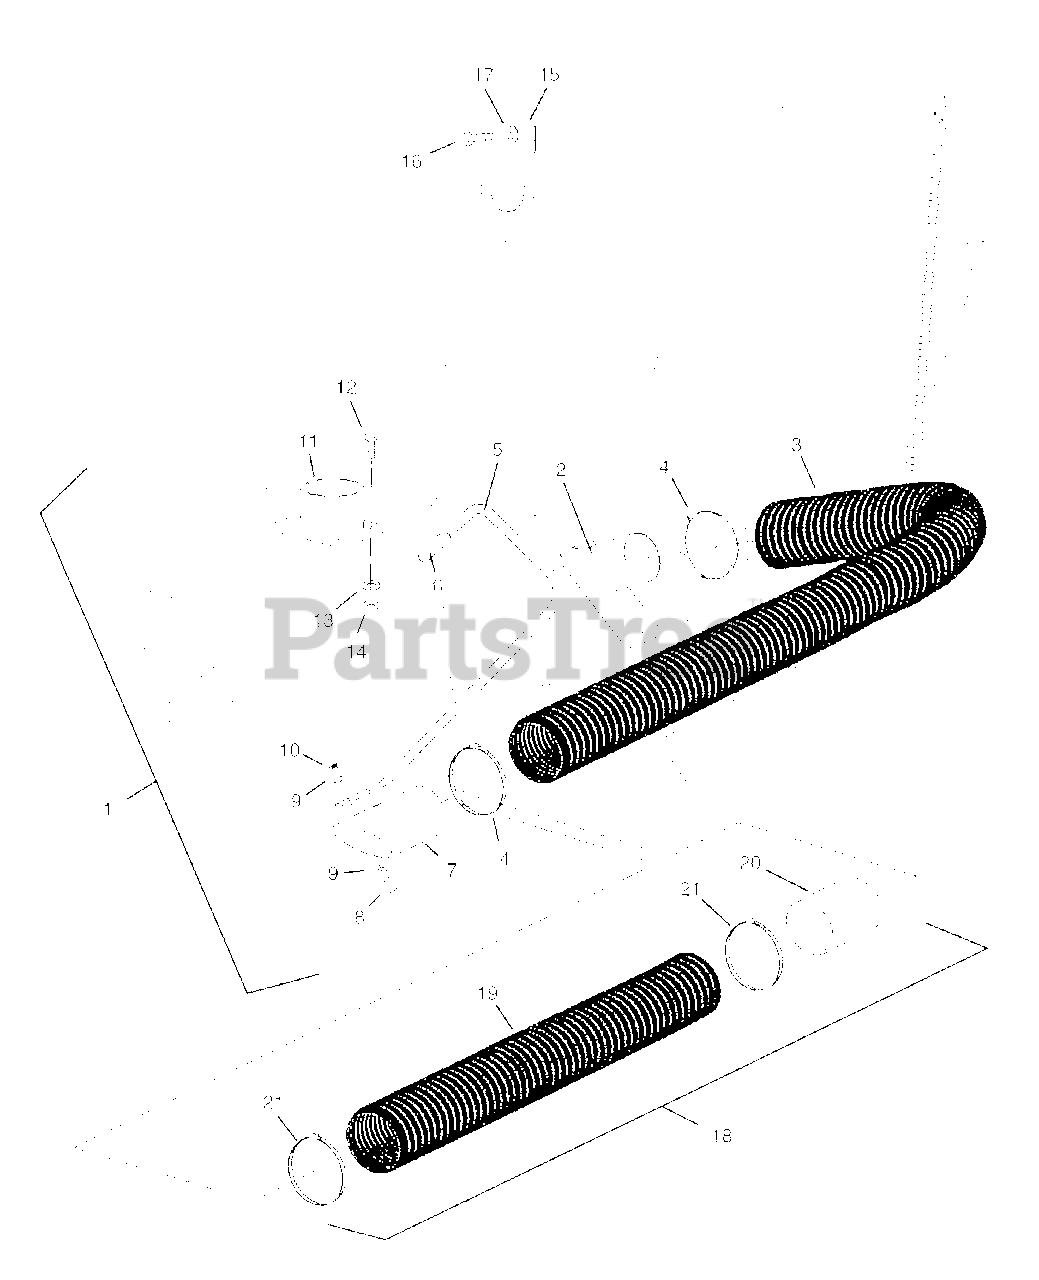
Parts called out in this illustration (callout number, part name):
1	Hand Vac Kit - 1050
2	Adapter Tube Weldment
3	Hose 6" x 10' Spring, Black
4	Hose Clamp
5	Nozzle Handle
6	Handle Grip
7	Nozzle Tube
8	Bolt-Hex .31-18 x .75 Grade 5
9	Washer-Flat-Steel .38 x .875 x .083
10	Nut-Locking .312-18
11	Nozzle Holder
12	Bolt-Hex .375-16 x 1.00 Grade 5
13	Washer-Flat-Steel .438 x 1.0 x .083
14	Nut-Locking .375-16
15	Flex Hose Hanger
16	Bolt-Hex .38-16 x 2.00 Grade 5
17	Washer-Lock .375 x .155
18	Hand Vac Extension Kit
19	Hose 6" x 10' Spring, Black
20	Flex Hose Insert
21	Hose Clamp
